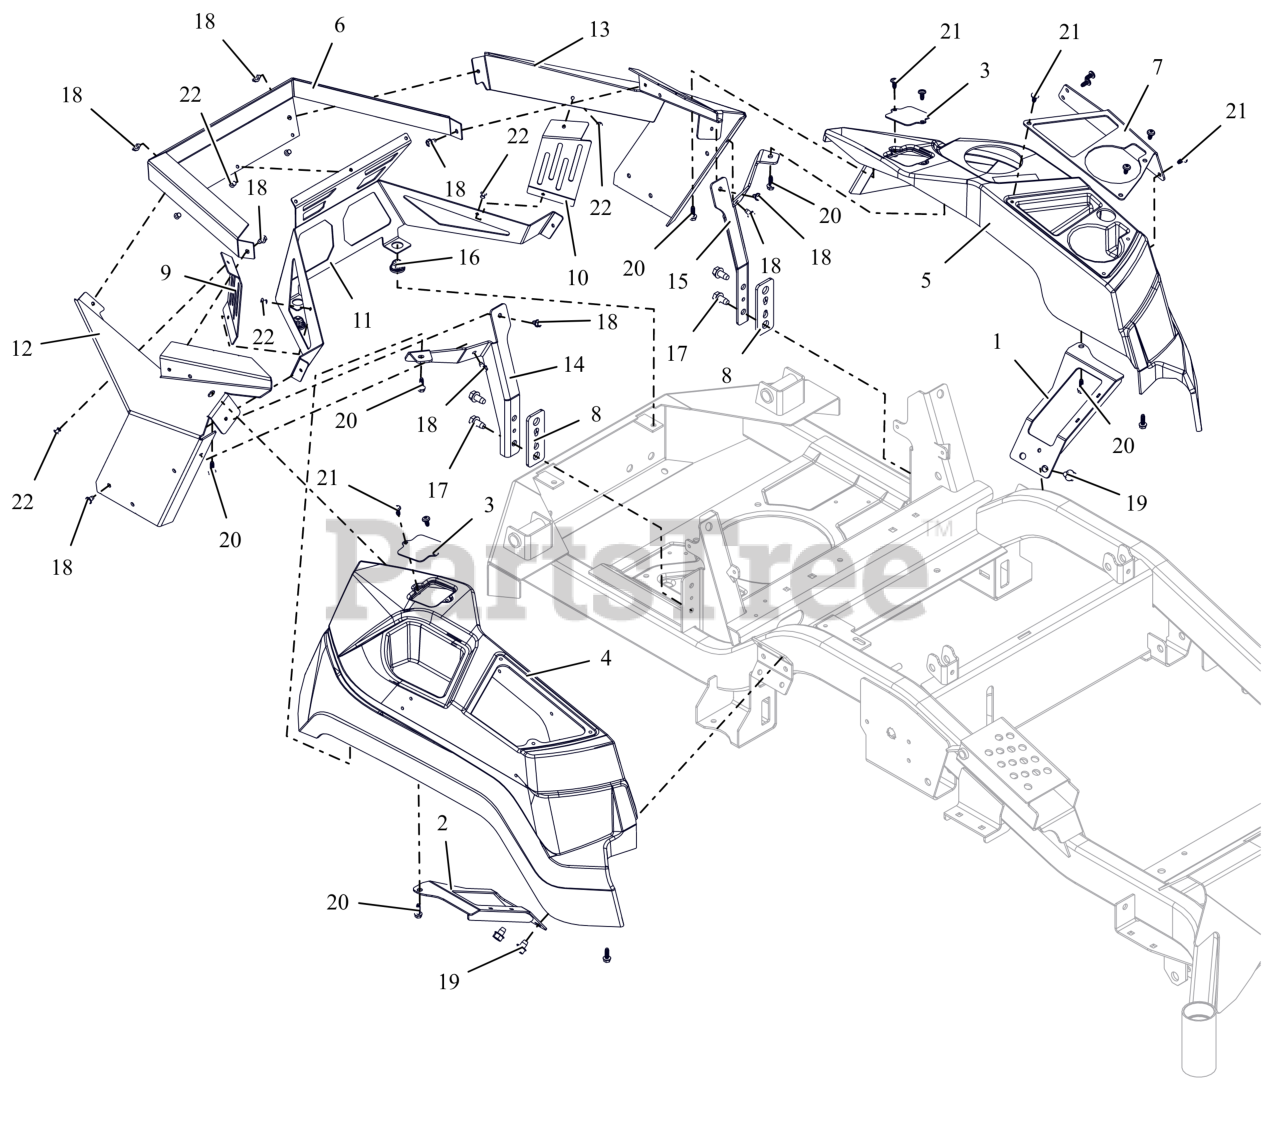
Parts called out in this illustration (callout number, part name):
1	WLDMT, LH FENDER MOUNT
2	WLDMT, RH FENDER MOUNT
3	PLATE, ROPS HOLE-HD
4	FENDER, RH APEX - 2017
5	FENDER, LH APEX
6	GUARD,ENGINE WRAP
7	PLATE, APEX CUP HOLDER COVER
8	PLATE, CONTROL PANEL SPACER
9	SHIELD,RH ENGINE GUARD VALVE
10	SHIELD,LH ENGINE GUARD VALVE
11	GUARD, ENGINE
12	PANEL, RH REAR FENDER MOUNT
13	PANEL, LH REAR FENDER MOUNT
14	BRKT, RH FENDER MTG (ORANGE)
15	BRKT, LH FENDER MOUNT (ORANGE)
16	GROMMET, 10MM BOLLHOFF
17	SCR,TAP .375-16X.75 HWH TR ZCC
18	SCR,TAP .25-20X.375 HWH TR ZCC
19	SCR,TAP .375-16X.50 HWH TR ZCC
20	SCR, PLASTITE .25-10X.75 ZCC
21	SCR-PAN .25-15X.50 6L H/LZB500
22	RIVET, .1875 AL/AL .126-.250
